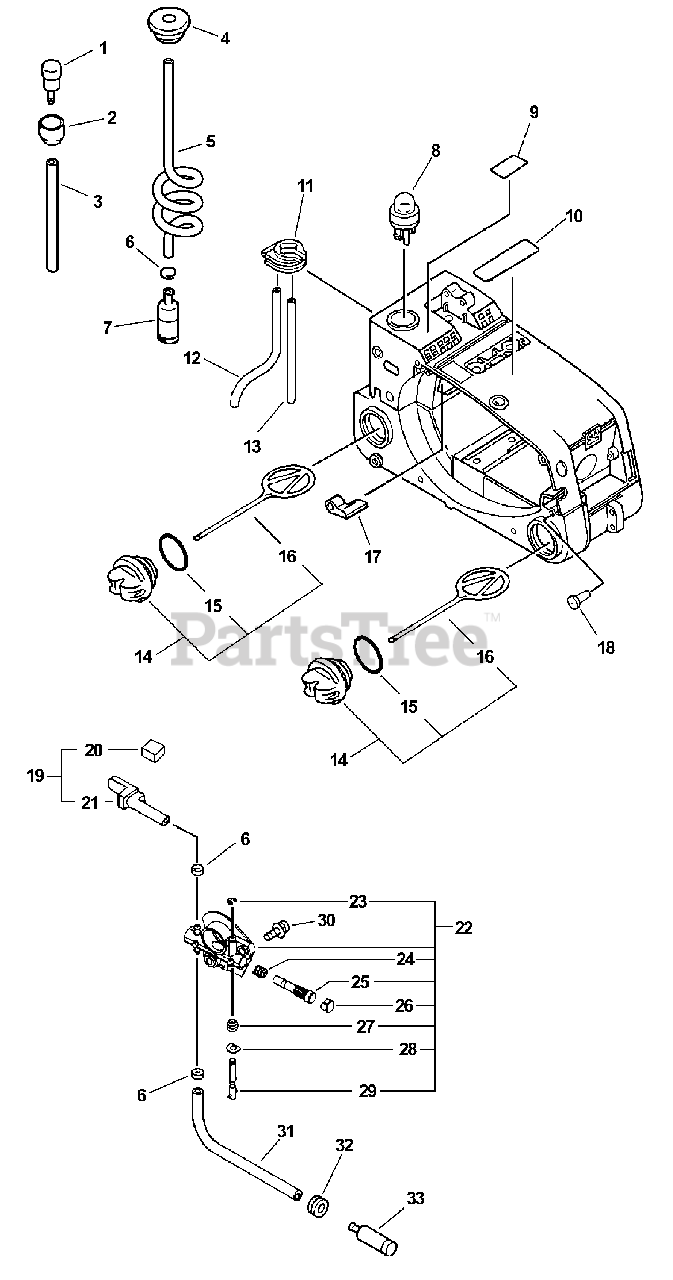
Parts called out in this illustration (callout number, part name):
1	VENT ASSY
2	HOLDER, VENT
3	PIPE, FUEL 3×5×150 BLACK
4	GROMMET, FUEL
5	PIPE, FUEL 3×6×160
6	CLIP Ø6.5 MM
7	FILTER, FUEL
8	BULB, PURGE
9	LABEL, PURGE PUMP
10	LABEL - CAUTION
11	BRACKET, BULB
12	PIPE, FUEL 2×4×42 CLEAR
13	PIPE, FUEL 3x-5x-70 BLACK
14	CAP ASSY, OIL
15	O-RING 25
16	CONNECTOR, CAP L= 60 MM
18	VENT ASSY
19	PIPE KIT, OIL
20	PAD, FOAM
21	PIPE, OIL OUTLET
22	AUTO-OILER ASSY
25	PLUNGER ASSY
26	CAP, OIL PUMP
29	ADJUSTER, OILER
30	SCREW 5×12
31	PIPE 3×6×115 BLACK
32	GROMMET
33	FILTER, OIL
